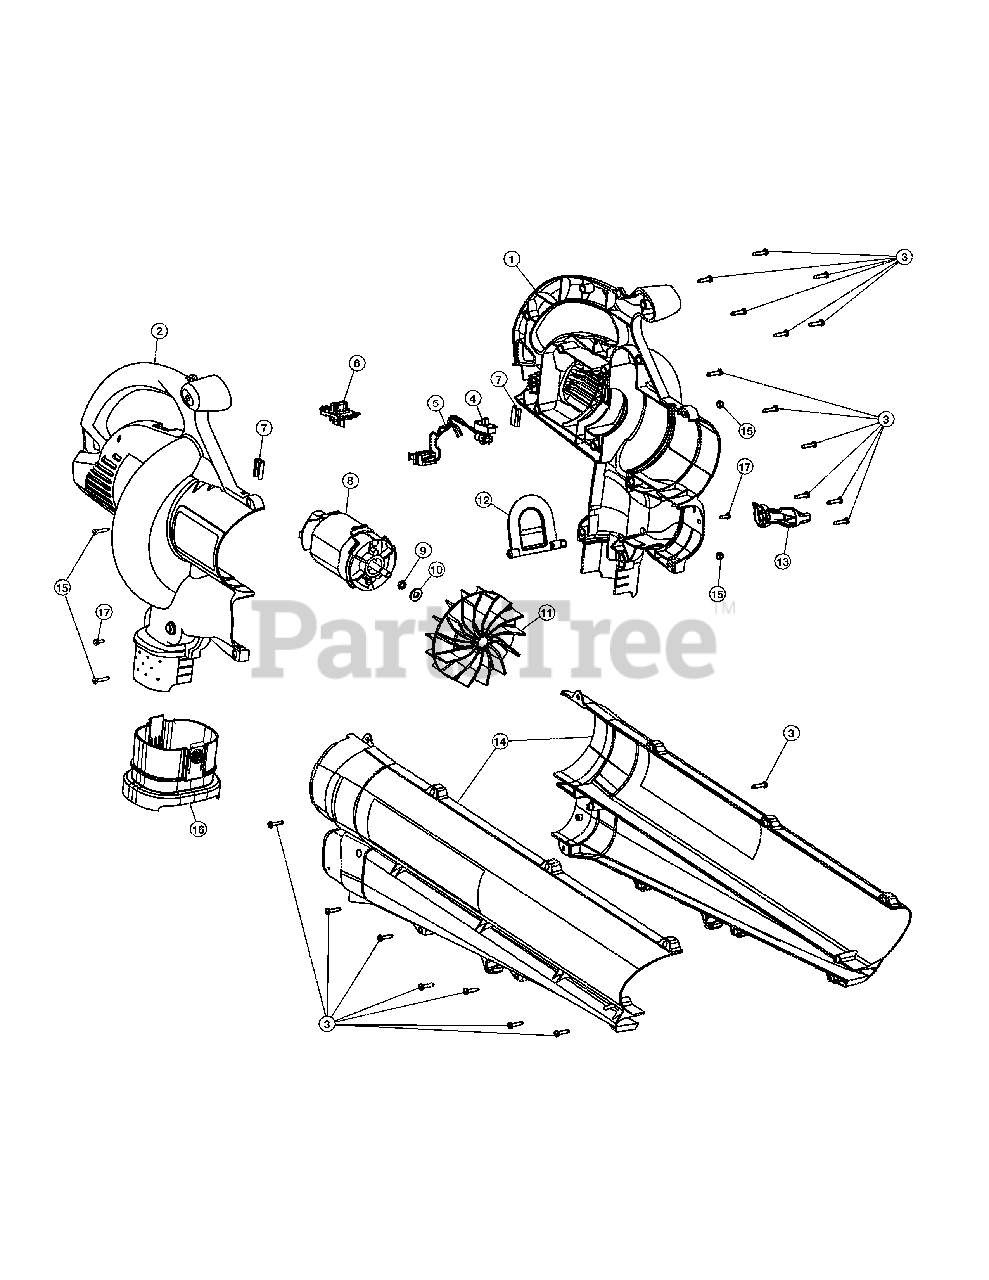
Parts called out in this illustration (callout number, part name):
1	Left Motor Housing
2	Right Motor Housing
3	Housing Screw
4	Switch Assembly
5	Power Connection Wire Assembly
6	Switch Lever
7	Rubber Cushion
8	Motor Assembly
11	Impeller
12	Mode Control Flapper
13	Mode Control Lever
14	Blower/ Vac Tube Assembly (Incl. 3)
15	Blower/ Vac Tube Mounting Hardware
16	Vacuum Bag Tube
